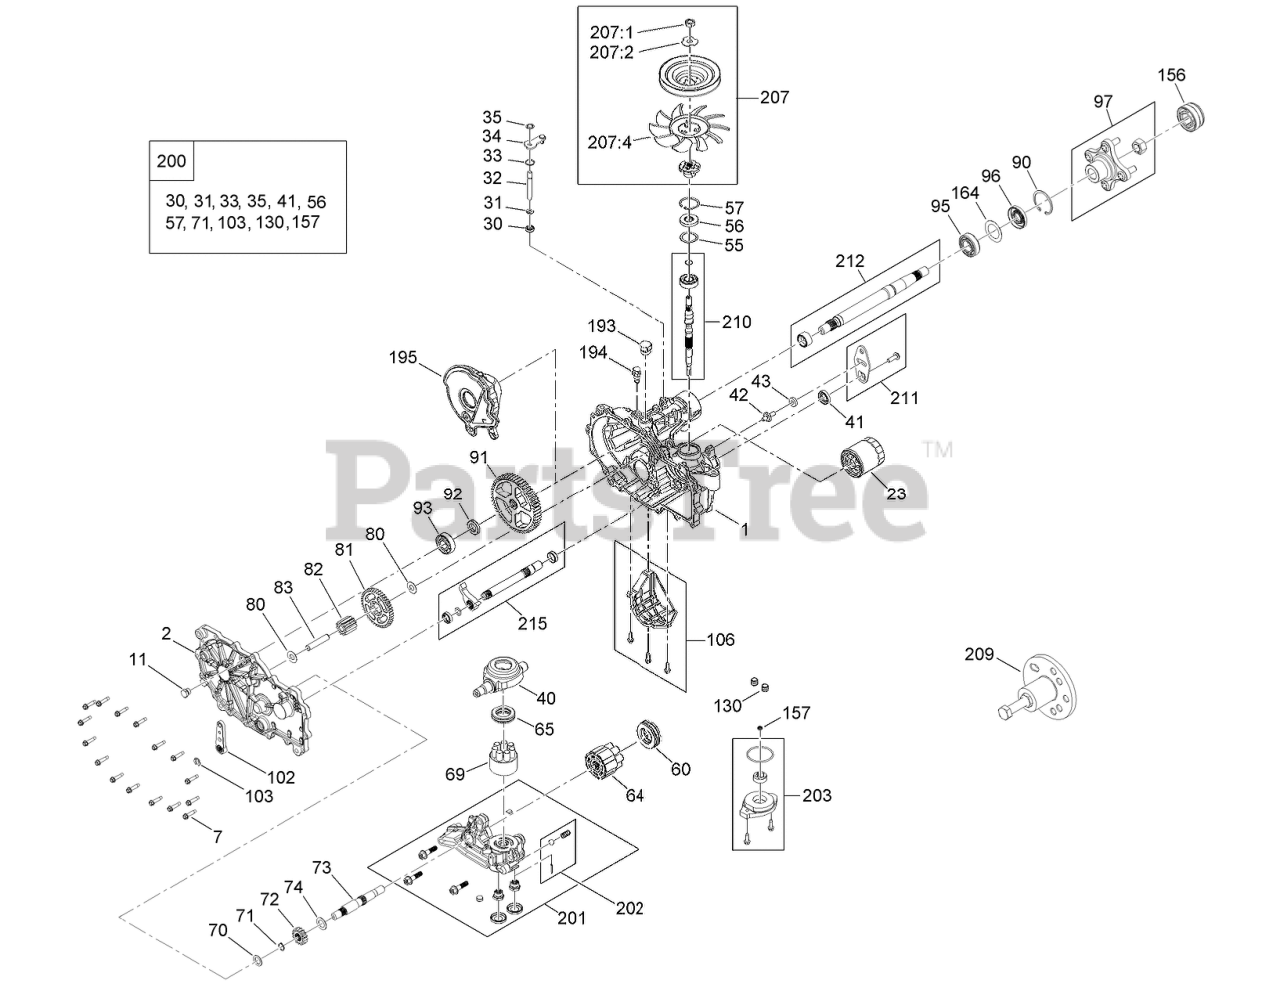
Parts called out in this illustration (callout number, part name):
1	LH MAIN HOUSING KIT
2	LH SIDE COVER KIT
7	SCREW-HHF
23	ELEMENT-OIL FILTER, HYD
30	SEAL-LIP
31	RING-RETAINING, EXTERNAL
32	ROD-BYPASS
33	RING-RETAINING, INTERNAL
34	ARM-BYPASS
35	RING-RETAINING, EXTERNAL
40	SWASHPLATE-TRUNNION
41	SEAL-LIP
43	PUCK-FRICTION
55	SPACER
56	SEAL-LIP
57	RING-RETAINING
60	BEARING-THRUST
64	CYLINDER BLOCK ASM KIT
65	BEARING-THRUST
69	PUMP BLOCK ASM
70	WASHER-FLAT
71	RING-RETAINING
72	GEAR-14T
73	SHAFT-MOTOR
74	WASHER
80	WASHER
81	GEAR-45T
82	GEAR-11T
83	PIN-JACKSHAFT
90	RING-RETAINING
91	GEAR-54T
92	SPACER
93	BEARING KIT
95	BEARING-BALL
97	HUB KIT
102	HANDLE-BRAKE
103	RING-RETAINING, EXT
106	FILTER GUARD KIT
130	TUBE-CHARGE
156	COVER-NUT, AXLE
157	GEROTOR SEAL KIT
164	SPACER
194	BREATHER FITTING ASM
195	LH INTERNAL EXPANSION TANK ASM
200	SEAL KIT
201	LH CHARGE CENTER SECTION KIT
202	CHARGE RELIEF KIT
203	CHARGE KIT
207	FAN AND PULLEY KIT
207:1	NUT-HJ
207:2	WASHER-SLOTTED
207:4	FAN 7.0 X 10 BLADE
210	INPUT SHAFT KIT
211	CONTROL ARM KIT
212	AXLE SHAFT KIT
215	INBOARD KIT
